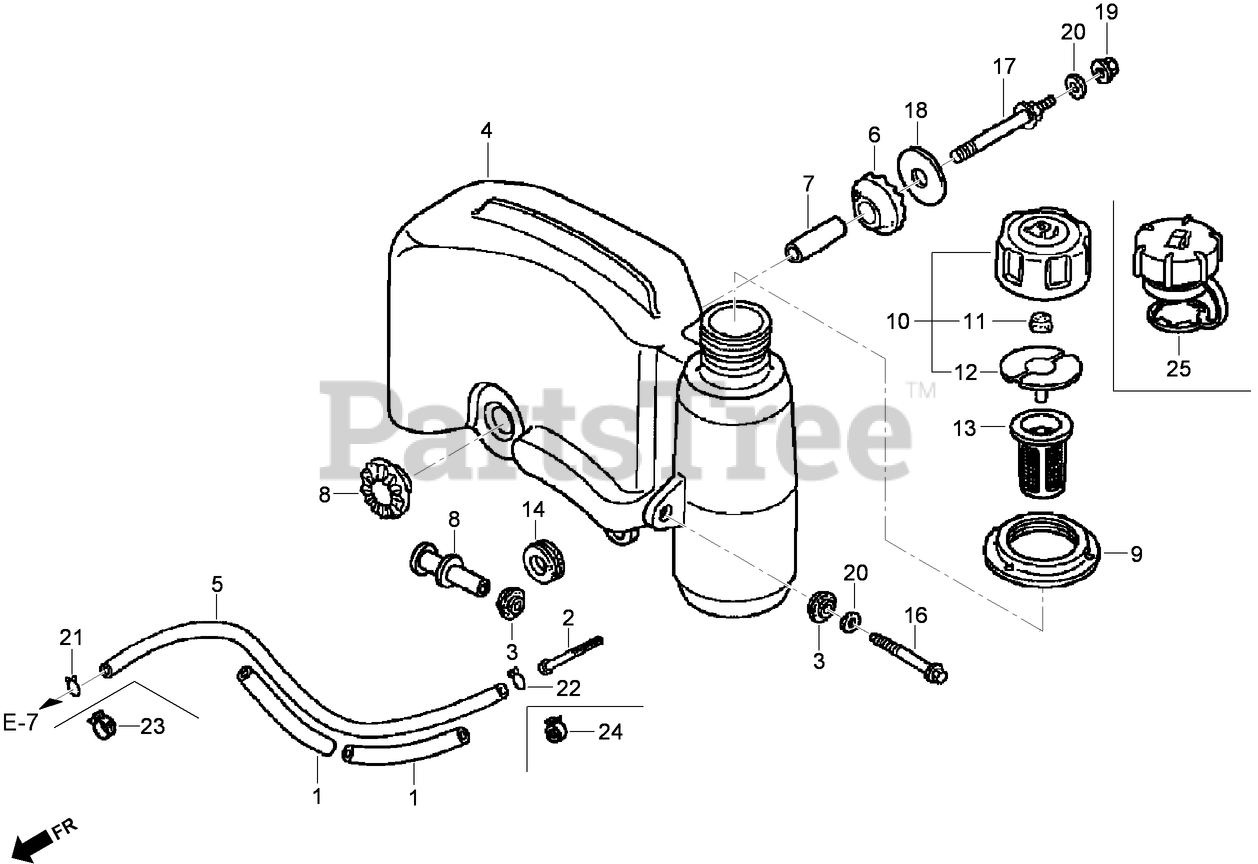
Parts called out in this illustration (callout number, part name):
1	SUPPORTER-RUBBER (107 mm)
2	FILTER-FUEL
3	RUBBER-SETTING, TANK
4	TANK-FUEL (Engine Serial No. Up To 1036455)
4	TANK-FUEL
5	TUBE-FUEL (Engine Serial No. Up To 1011283)
5	TUBE-FUEL (FKM) (Engine Serial No. From 1011284)
6	RUBBER B-MOUNTING, TANK
7	COLLAR-SET, TANK
8	COLLAR-TANK
9	RUBBER-MOUNTING, TANK (Engine Serial No. Up To 1036455)
10	FUEL TANK CAP ASM
11	Sponge-BREATHER, Fuel Cap
12	GASKET-CAP, FUEL
13	GAUGE-LEVEL, FUEL
14	CUSHION-FENDER, R R
16	BOLT-FLANGE (6X47) (C T200)
17	BOLT-STAY, TANK
18	WASHER-MOUNTING, TANK
19	NUT-FLANGE (6 mm)
20	WASHER-PLAIN (6 mm)
21	CLIP-TUBE (B8)
22	CLIP-TUBE (C11) (engine serial numbers up to 6901760)
23	CLAMP-TUBE (D8) (engine serial numbers starting at 3698327)
24	CLAMP-TUBE (D105) (Engine Serial No. From 1011284)
25	FUEL TANK CAP ASM
